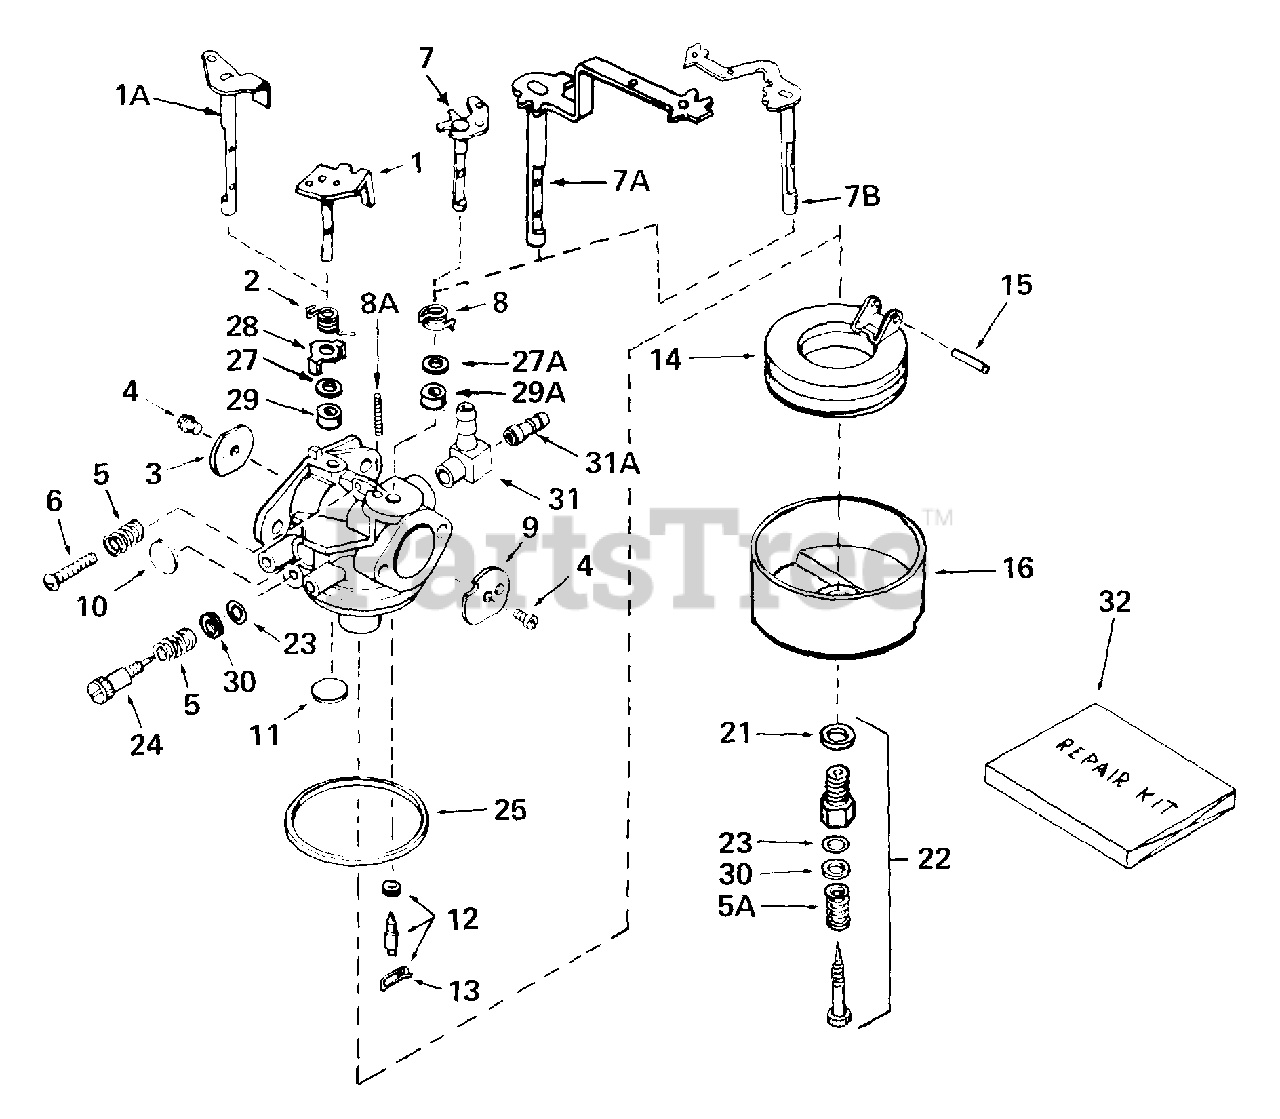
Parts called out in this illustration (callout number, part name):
1	"Shaft & Lever Assy., Throttle
2	Spring, Throttle return
3	Shutter, Throttle
4	Screw, Throttle & choke shutter
5	Spring, Adjustment screw
5A	Spring, Adjustment screw
6	Screw, Idle regulating
7	Shaft & Lever Assy., Choke
8	Spring, Choke return
9	Shutter, Choke
10	Plug, Welch
11	Plug, Welch
12	Inlet Needle, Seat & Clip Assy.
13	Clip, Inlet needle
14	Float, Carburetor
15	Shaft, Float
16	Bowl, Float
21	Gasket, Bowl-to-body
22	Adjustment Screw Assy., Main
23	"O" Ring, Adjustment screw
24	Screw, Idle adjustment
25	Gasket, Bowl-to-body
28	Retainer, Seal
29	Seal, Dust
30	Washer, Flat
31	Fitting, Fuel
32	Repair Kit
